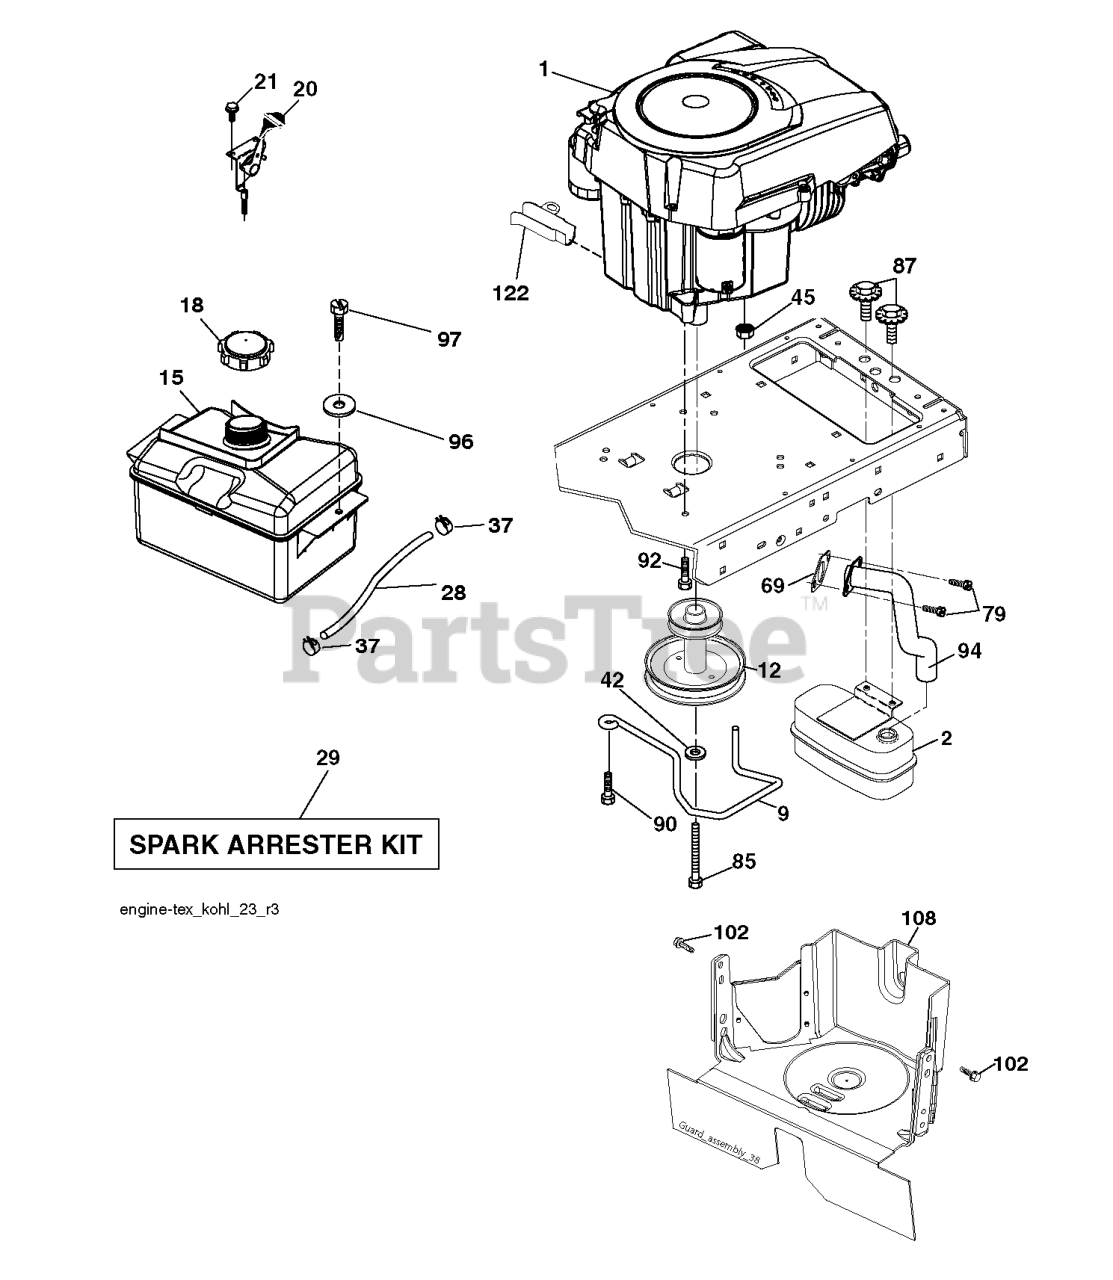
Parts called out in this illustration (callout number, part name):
2	MUFFLER.SINGLE.CYL.KOHL/B&S
9	KEEPER.BELT.ENGINE.4.2
12	PULLY ENGINE
15	RP TANK FUEL FRT 1.5 GAL
18	CAP ASM.FUEL.2.25"FR.
20	CONTROL.TH/CK.C.
21	SCREW.#10 X 0.750.BOS
28	LINE.FUEL.20
29	KIT.SPARK ARRESTOR 794945 B&S
37	HOSE CLAMP
42	LOCKWASHER
45	NUT
69	GASKET.EXHAUST.KOHLER
79	SCREW.SOCKET HD.5/16-1
85	BOLT HEX 7/16-20X4-1/4"
87	BOLT.5/16-18UNCX3/4 W/SEMS.BLK
90	SCREW 3/8-16X1
92	SCREW 3/8-16X1
94	RP.TUBE.EXHAUST.KOHL.COURAGE
96	WASHER
97	SCREW HEXWSHR 1/4-20X3/4
102	SCREW 5/16-18X1
108	COVER PULLEY
122	EXTENSION DRAIN OIL
